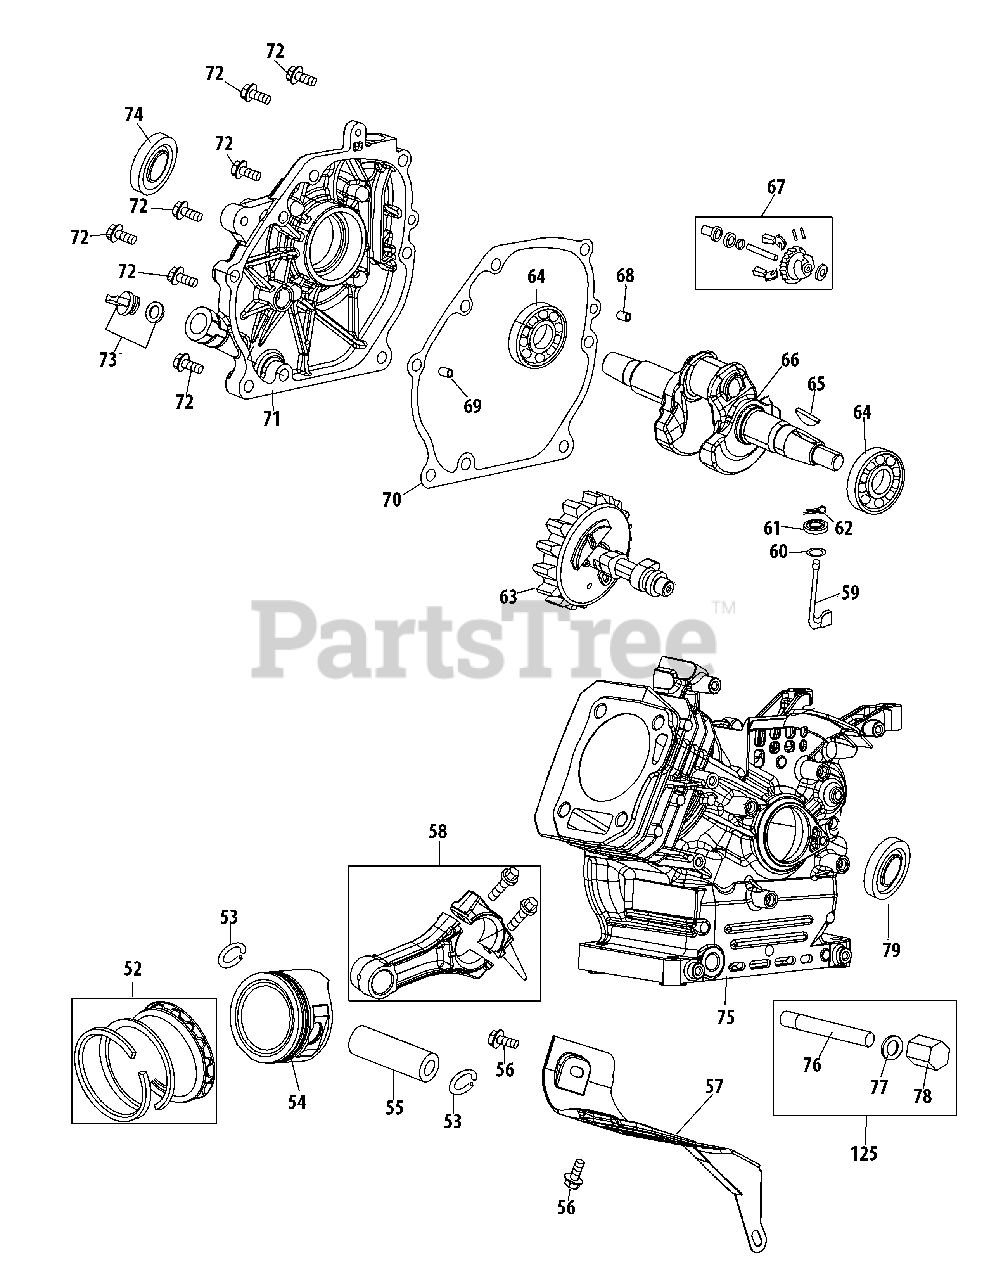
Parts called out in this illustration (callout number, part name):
52	Piston Ring Set
53	Piston Pin Snap Ring
54	Piston
55	Piston Pin
56	Bolt M6×12
57	Air Shield
58	Connecting Rod Assembly
59	Governor Arm Shaft
60	Washer 5.2×1.9
61	Governor Seal
62	Cotter Pin
63	Camshaft Assy.
64	Radial Ball Bearing, 6205
65	Woodruff Key
66	Crankshaft Kit
67	Governor Gear/Shaft Assembly
68	Dowel Pin 7×14
69	Dowel Pin 9×14
70	Crankcase Cover Gasket
71	Cover Comp, Left Crankcase
72	Bolt M8×32
73	Oil Fill Plug Assembly
74	Oil Seal, 25×41.25×6
75	Crankcase Cover Kit
76	Oil Drain Pipe Assy.
77	Washer 10×16×1.5
78	Oil Drain Plug
79	Oil Seal 25×41.25×6
125	Oil Drain Assembly
